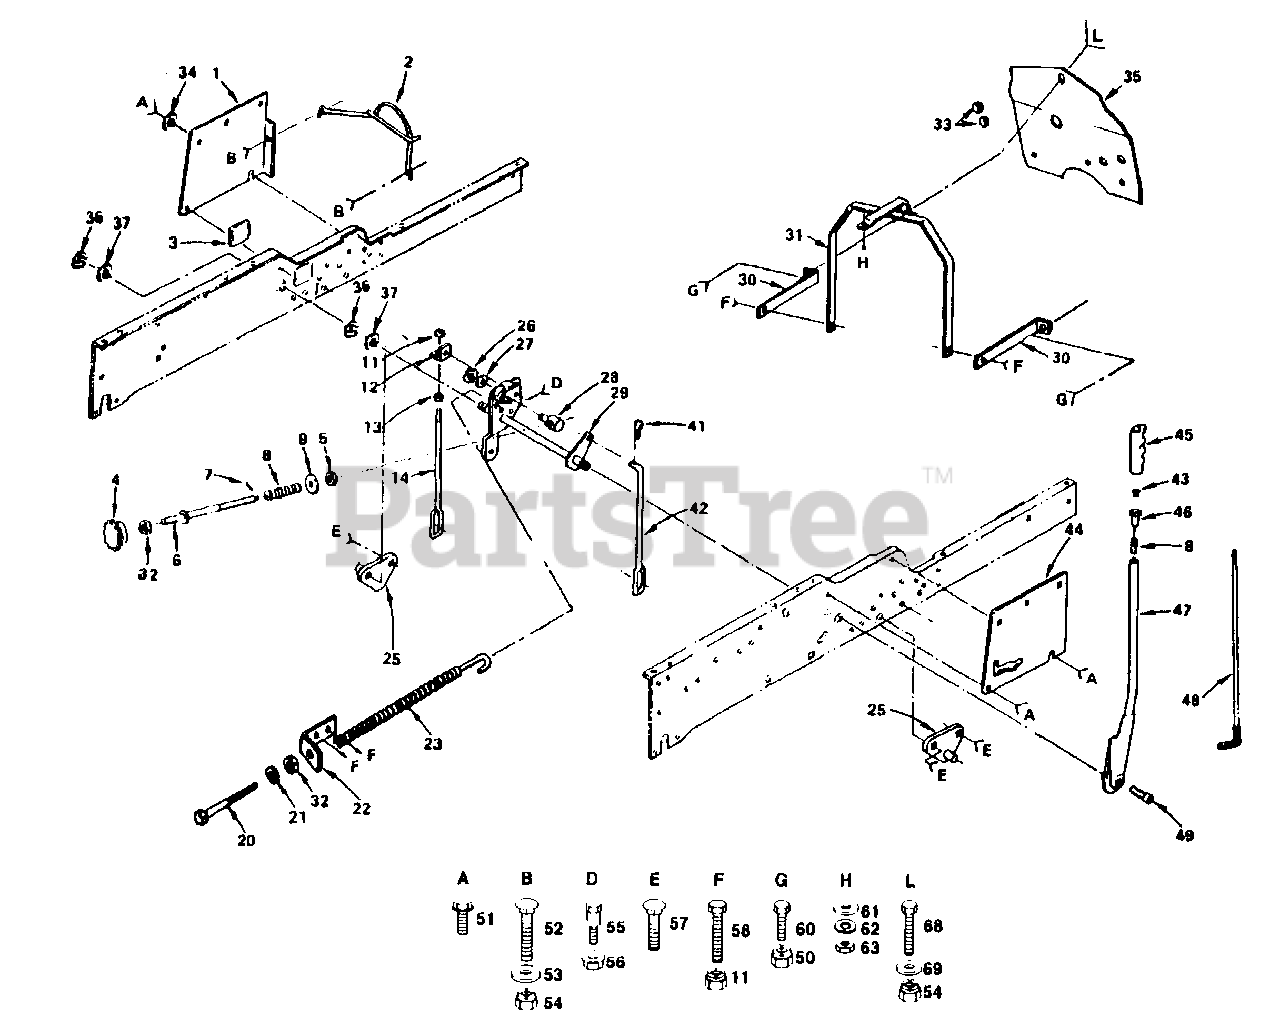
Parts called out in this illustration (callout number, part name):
1	Panel, Side, L.H.
2	Guard Assembly, Belt, Engine
3	Cover, Access
4	Handle, Adjust, Lift
6	Rod, Adjust, Lift
7	Pin, Cotter
8	Spring
9	Washer 13/32 x 5/8 x 16 Gauge
11	Locknut, Hex w/Washer 3/8-16
12	Bracket, Lift, L.H.
13	Nut, Hex 3/8-16
14	Link, Lift, L.H.
15	Screw, Thdrol. 3/8-16 x 3/4
20	Bolt, Adjust, Spring, Assist
21	Washer 13/32 x 13/16 x 16 Gauge
22	Bracket, Spring, Assist
23	Spring Assembly, Assist, Lift
25	Bracket, Suspension
27	Washer 15/32 x 3/4 x 16 Gauge
28	Trunnion, Stop Depth
30	Bracket, Shield, Heat, Side
31	Assembly, Support, Dash
32	Nut, Hex Jam 3/8-16
33	Grommet
34	Washer, Lock Ext. Tooth 3/8
35	Base, Shield, Heat
37	Washer 29/32 x 1-1/4 x 16 Gauge
41	Retainer, Spring
42	Link, Lift, R.H.
43	Button, Plunger
44	Panel, Side, R.H.
45	Grip, Handle
46	Plunger, Lever, Lift
47	Lever Assembly, Lift
48	Rod Assembly, Lever
49	Bolt, Hex 3/8-16 x 1-1/2
50	Nut, Crownlock 1/4-20
51	Screw, Hex Washer Thd. 3/8-16 x 1/2
52	Bolt, Carriage 5/16-18 x 1
53	Washer 11/32 x 1 x 10 Ga.
54	Nut, Lock wlns 5/16-18
55	Bolt, Shoulder
56	Nut, Hex Flange 1/4-20
57	Screw Thdrol 3/8-16 x 3/4
58	Bolt Fin Hex 1/4-20 x 1/2 Gr. 5
59	Bolt, Hex 3/8-16 x 1
60	Bolt, Hex 1/4-20 x 1/2
61	Washer 9/32 x 3/4 x 16 Ga.
62	Washer, Lock 1/4
63	Nut, Hex 1/4-20
68	Bolt, Hex 5/16-18 x 3/4
69	Washer 11/32 x 3/4 x 16 Gauge
